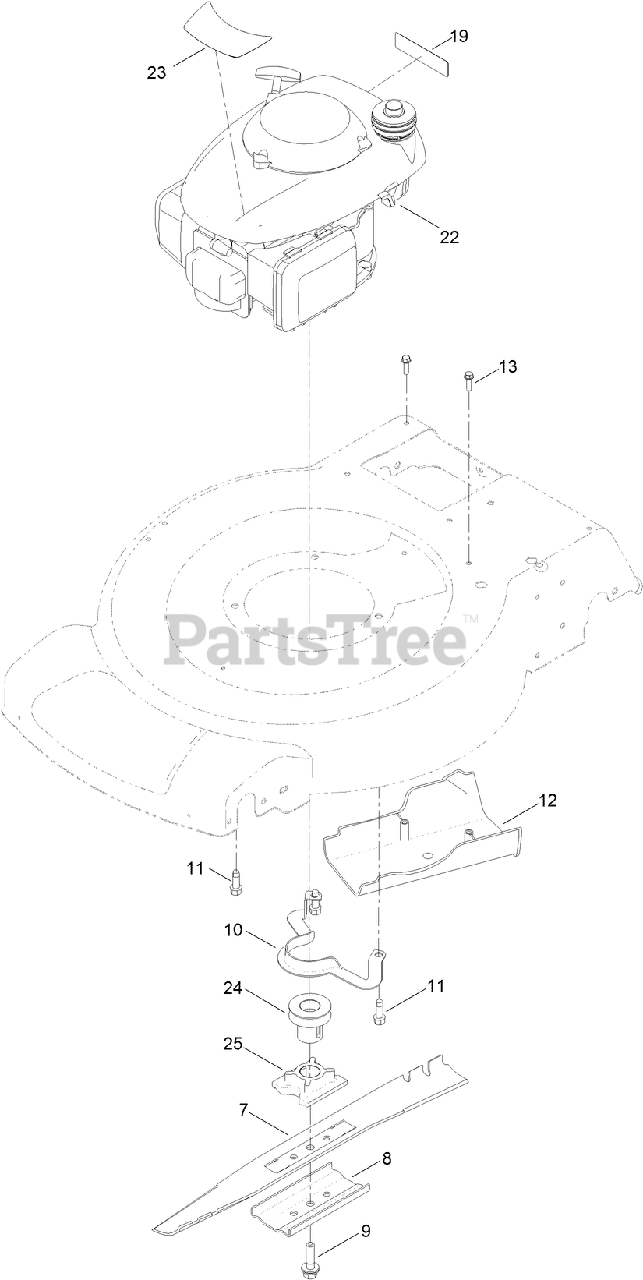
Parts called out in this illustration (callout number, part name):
8	SUPPORT-BLADE
9	BOLT-BLADE
10	GUIDE-BELT
11	SCREW-TAPTITE
12	COVER-BELT
13	SCREW-HWH
19	DECAL-ARRESTER, SPARK
23	DECAL-ENGINE
24	PULLEY
25	RETAINER-BLADE
